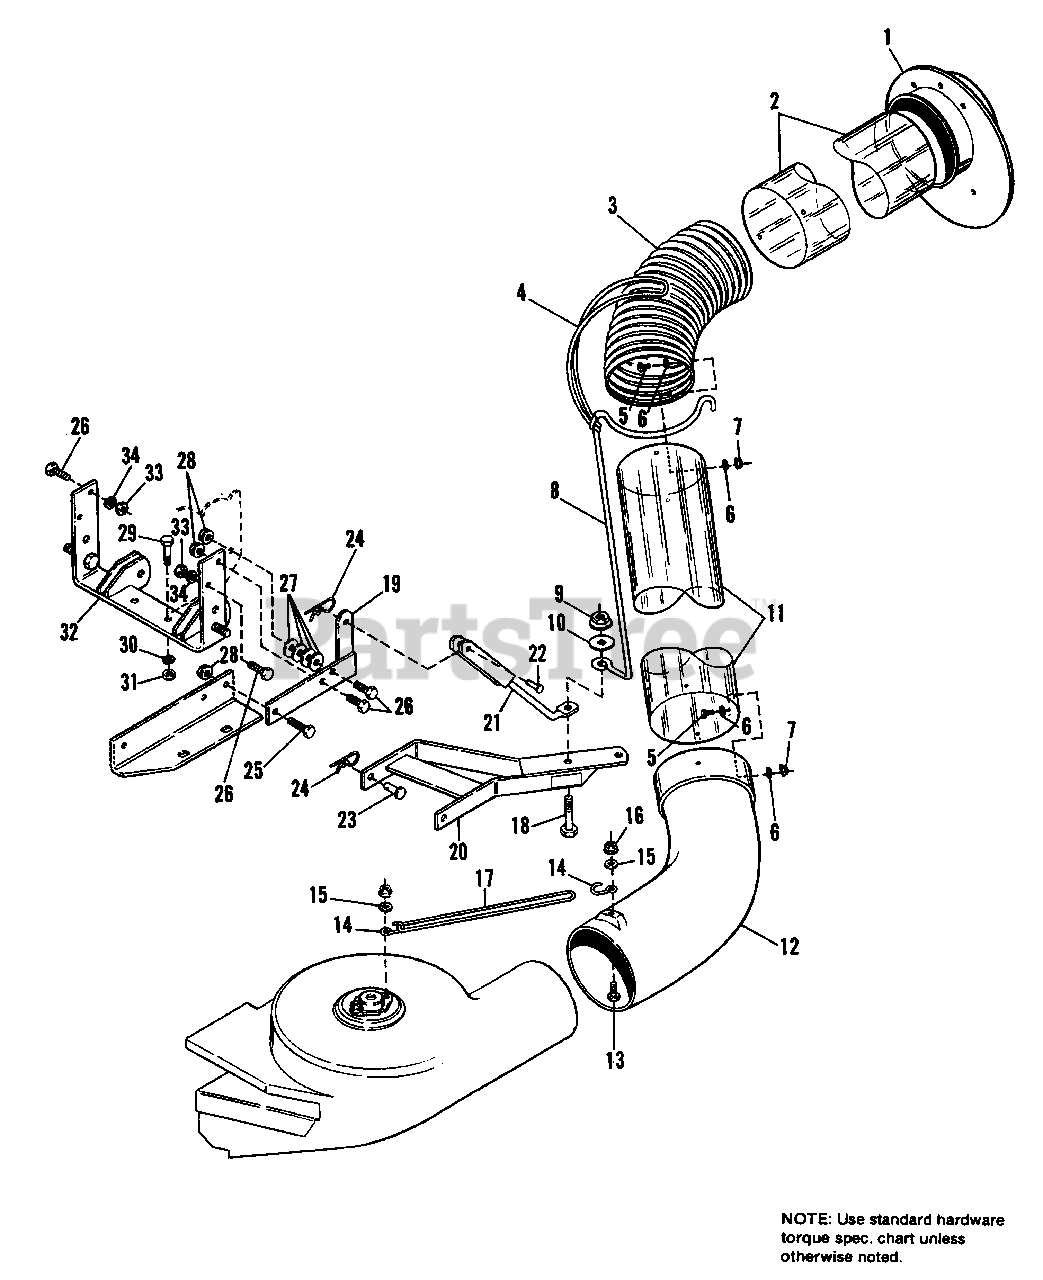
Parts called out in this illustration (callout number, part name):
1	CONNECTOR, Cart (7.0" Dia.)
5	SCREW, Truss Hd., #10-32 x 1/2
6	WASHER, Plain, #10
7	NUT, Hex, & Washer Assy., #10-32
8	SUPPORT, Tube
9	NUT, Hex, Flange, 1/2-13
11	TUBE ASSY. (Mfg. No. 1691610) (w/decal)
11	TUBE ASSY. (Mfg. No. 1691609) (w/decal)
13	CAPSCREW, Hex, 5/16-18 x 5/8
15	WASHER, Plain, 5/16
16	NUT, Flange, Lock, 5/16
18	CAPSCREW, Hex Hd., 1/2-13 x 2
19	SUPPORT ASSY.
20	DRAWBAR ASSY.
21	SUPPORT ASSY., Drawbar
22	PIN, Round Hd.
23	PIN, Yoke
24	CLIP, Spring
25	CAPSCREW, Hex Hd., 7/16-14 x 1-3/4
26	CAPSCREW, Hex Hd., 7/16-14 x 1-1/4
27	WASHER, Flat
28	NUT, Flange
29	CAPSCREW, Hex Hd., 1/2-13 x 1-1/4
30	WASHER, Lock, 1/2
31	NUT, Hex, 1/2-13
32	BRACKET ASSY., Hitch
33	NUT, Hex, 7/16-14
34	WASHER, 7/16
